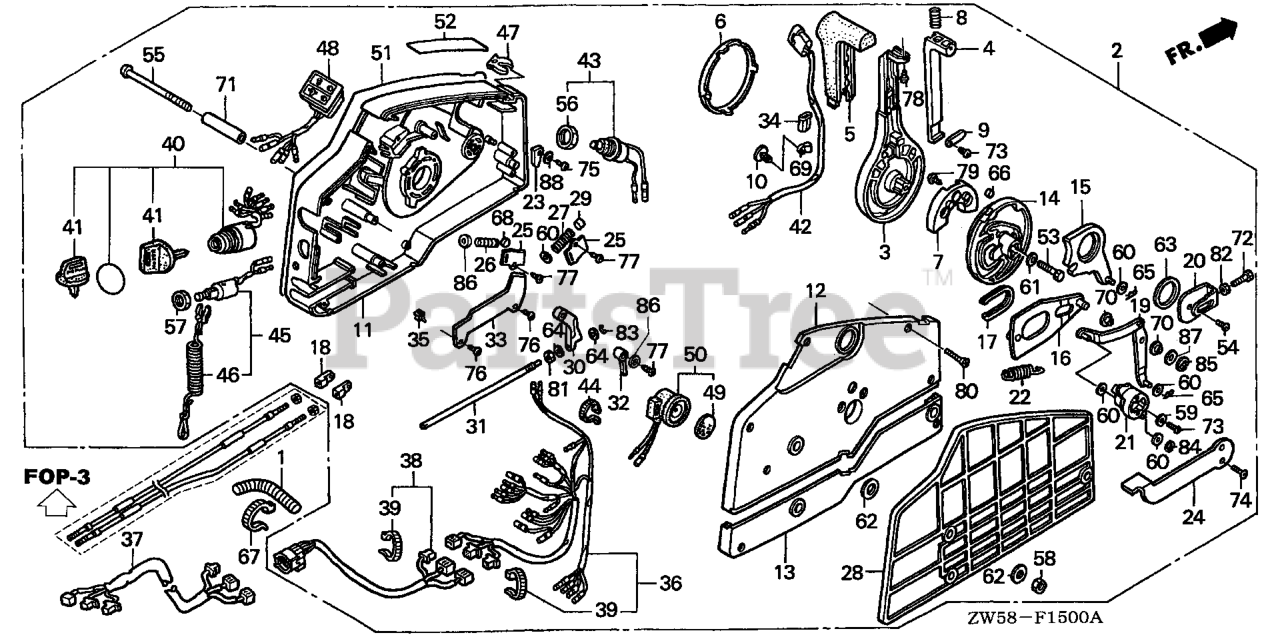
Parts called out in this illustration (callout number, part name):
1	TUBE, CORRUGATED (28MM)
2	BOX ASSY., REMOTE CONTROL (NHK MEC)
2	BOX ASSY., REMOTE CONTROL (2-LED) (P/T) Use from Frame SN 1302131.
3	HANDLE, REMOTE CONTROL
4	LEVER, HANDLE LOCK
5	GRIP, REMOTE CONTROL HANDLE
6	CAP, HANDLE
7	BLOCK, NEUTRAL LOCK
8	SPRING, REMOTE CONTROL HANDLE
9	PLATE, LEVER SETTING
10	CLAMP, HARNESS
11	HOUSING, REMOTE CONTROL BOX (A)
12	HOUSING, REMOTE CONTROL BOX (B)
13	HOUSING, REMOTE CONTROL BOX (C )
14	WHEEL, CONTROL
15	ARM, SHIFT LINK
16	PLATE, SLIDING
17	COLLAR, SLIDING PLATE
18	PIVOT, SHIFT
19	ARM, LINK JOINT
20	BRACKET, LINK JOINT
21	WHEEL, ACCELERATOR
22	SPRING, ACCELERATOR WHEEL
23	CAM, STARTER SWITCH
24	LEVER, IDLE
25	PLATE, SPRING SETTING
26	SPRING, SHIFT CLICK
27	SPRING, CHOKE RETURN
28	SPACER, REMOTE CONTROL BOX
29	SPACER, CLICK SPRING
30	BLOCK, THROTTLE FRICTION
31	BOLT, FRICTION
32	SPACER, NEUTRAL SWITCH
33	CLAMP, POWER TILT CORD
34	PIPE, HARNESS GUIDE
35	SPACER, CABLE CLAMP
36	CABLE ASSY., REMOTE CONTROL (B) Use from Frame SN 1300029.
37	CABLE ASSY., REMOTE CONTROL EXTENSION Use from Frame SN 1300029.
38	CABLE ASSY., SWITCH PANEL
39	TIE, CABLE (NATURAL 2.4X92) Use up to Frame SN 1300359.
40	SWITCH ASSY., COMBINATION DUAL QTY = (2) (SINGLE)
41	KEY ASSY., COMBINATION SWITCH (35100-ZV5-003 ONLY) DUAL QTY = (4) (SINGLE)
42	SWITCH ASSY., POWER TRIM-TILT
43	SWITCH ASSY., SOLENOID
44	BAND (BLACK 3.5X140)
45	SWITCH ASSY., EMERGENCY STOP
46	WIRE, EMERGENCY (SINGLE) (DUAL)
47	CLIP, EMERGENCY LOCK
48	LAMP ASSY., INDICATION (2-LED)
49	PLATE, TURN SIGNAL BUZZER DUAL QTY = (2) (SINGLE)
50	BUZZER, WARNING DUAL QTY = (2) (SINGLE)
51	PLATE, REMOTE CONTROL (CAUTION=SILVER)
52	MARK, FAST IDLE
53	BOLT, HEX. (8X35) Use up to Frame SN 4800712.
54	SCREW, PAN (6X10)
55	SCREW (6X95)
56	NUT, HEX. (20MM) Use up to Frame SN 1300359.
57	NUT, HEX. (16MM) DUAL QTY = (2) (SINGLE)
58	NUT, HEX. (6MM)
59	WASHER, PLAIN (5MM)
60	WASHER, PLAIN (6MM) Use up to Frame SN 4800342.
61	WASHER, PLAIN (8MM) Use up to Frame SN 4800712.
62	WASHER (6MM)
63	WASHER (28MM)
64	WASHER, PLAIN (4MM) Use up to Frame SN 4800712.
65	PIN, LOCK (6MM)
66	PIN (6X6)
67	BAND, SELF-LOCK Use from Frame SN 3000253.
68	ROLLER, CLICK
69	CLIP, WIRE HARNESS (6.3MM)
70	COLLAR, LINK JOINT
71	COLLAR, DISTANCE (6X10X43.5)
72	BOLT, HEX. (5X16)
73	SCREW, PAN (5X10)
74	SCREW, OVAL (5X12) Use up to Frame SN 4800712.
75	SCREW, TAPPING (4X10)
76	SCREW, TAPPING (5X8) (FOR SILVER MUFFLER)
77	SCREW, TAPPING (5X10)
78	SCREW, TAPPING (5X12)
79	SCREW, TAPPING (6X16)
80	SCREW, TAPPING (5X25)
81	NUT, HEX. (6MM)
82	NUT, HEX. (5MM)
83	E-RING (3MM)
84	E-RING (4MM)
85	E-RING (7MM)
86	WASHER, PLAIN (5MM)
87	WASHER, PLAIN (8MM) Use up to Frame SN 4800712.
88	WASHER, PLAIN (4MM) Use up to Frame SN 4800712.
